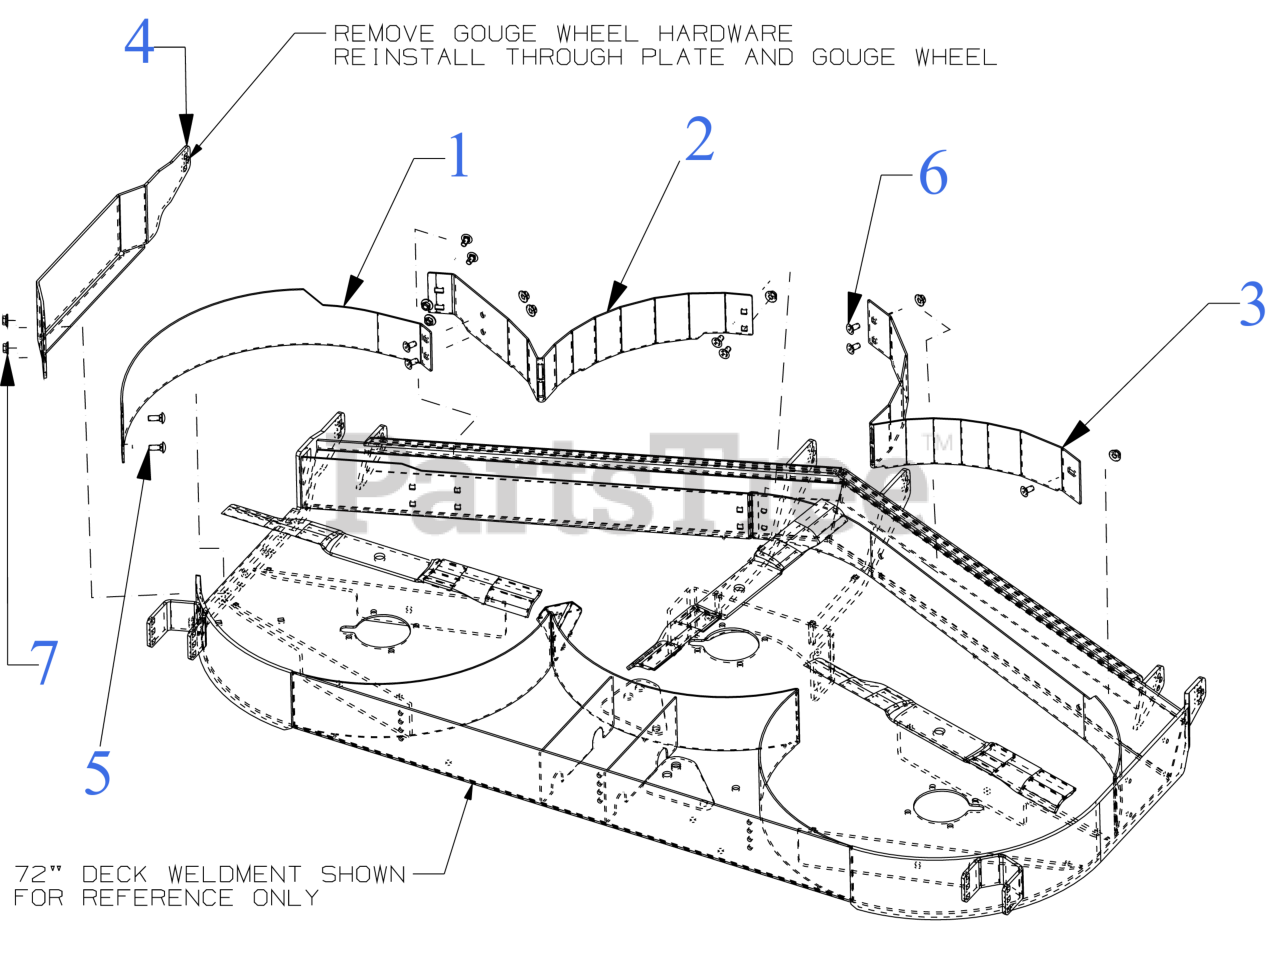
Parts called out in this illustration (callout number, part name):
4	BLOCKER PLATE 72"
5	CARRIAGE BOLT 3/8-16 x 1.00 GR5
6	CARRIAGE BOLT 3/8-16 x .75
7	FLANGE LOCK NUT
